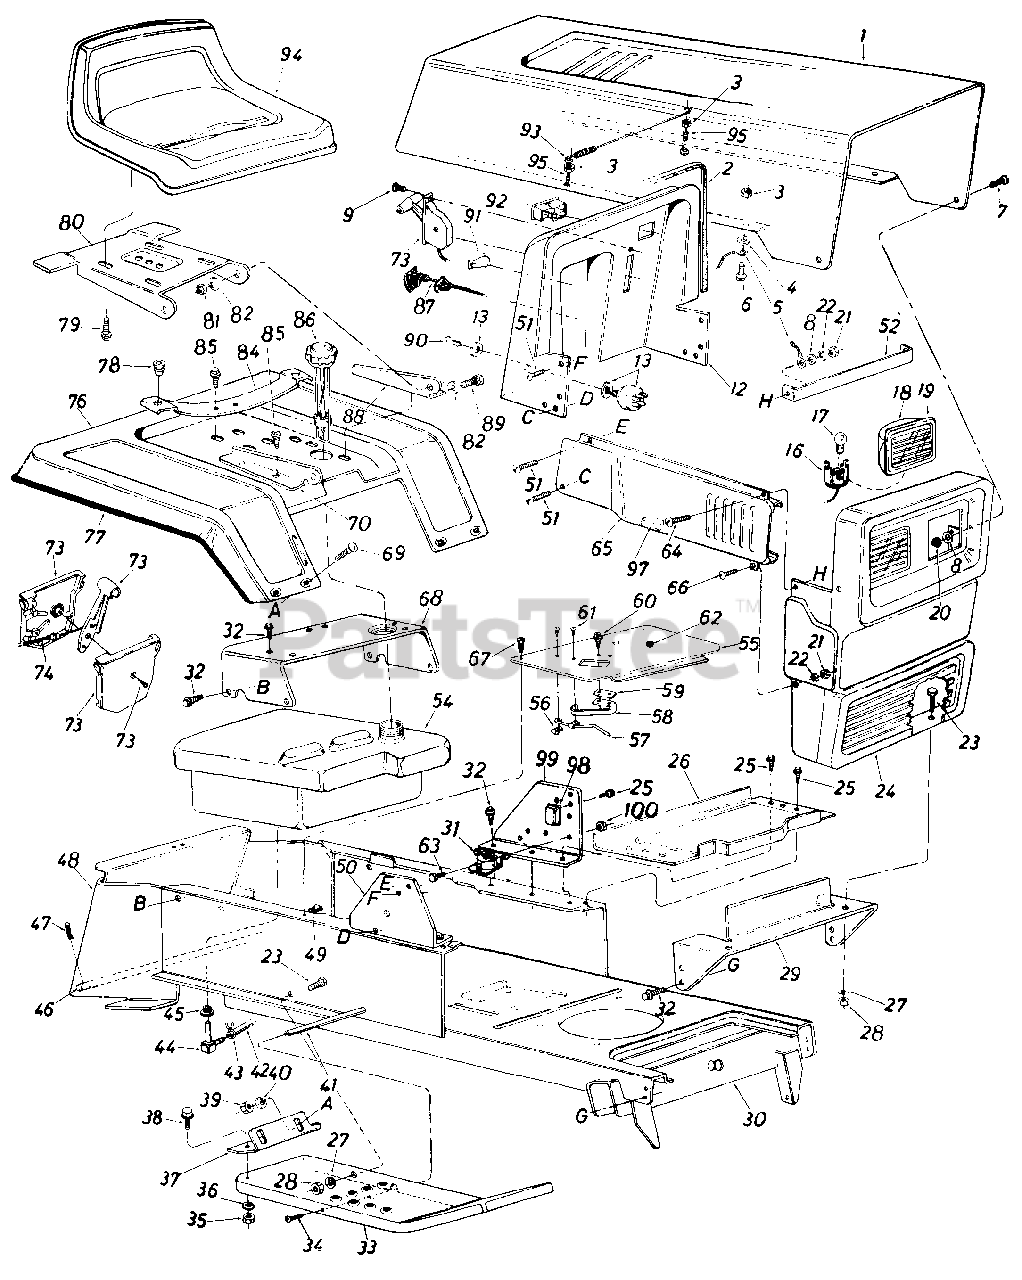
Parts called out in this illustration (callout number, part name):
1	Hood
2	Trim Strip-27" Lg.
3	Hex Sems Nut #10-24 Thd.
4	Fl-Wash. .20" I.D. x .41" O.D.
5	Hood Stop
6	Truss Hd. Mach. Scr. #10-24 x.50" Lg.*
7	Hex Bolt 1/4-20 x .62" Lg.*
8	Fl-Wash. 1/4" I.D.*
9	Truss Mach. AB-Tap Scr. #10 x .50" Lg.
12	Dash Ass'y.
13	Ignition Switch
16	Socket
17	Lamp
18	Headlight Housing
19	Lens
20	Hex L-Nut 1/4-20 Thd.
21	Hex Nut 1/4-20 Thd.*
22	L-Wash. 1/4" I.D.*
23	Hex Bolt 5/16-18 x .75" Lg.*
24	Grille
25	Hex Wash. Hd. Scr. 1/4" x .50" Lg.
26	Battery Plate
27	L-Wash. 5/16" I.D.*
28	Hex Nut 5/16-18 Thd.*
29	Grille Mounting Bracket
30	Lower Frame Ass'y.
31	Solenoid
32	Hex Thd. Rolling Scr. 5/16-24 x .75" Lg.
33	Running Board-R.H.
34	Truss Mach. Scr. 5/16-18 x .75" Lg.*
35	Hex Nut 5/16-18 Thd.*
36	Bell-Wash. .34" I.D. x .87" O.D.
39	Hex Nut 1/4-20 Thd.*
40	L-Wash. 1/4" I.D.*
41	Running Board Rod
42	Fuel Line 40" Lg.
43	Hose Clamp 3/8"
44	90ø Nipple
45	Bushing
46	Hitch Rod
47	Internal Cotterpin
48	Hitch Plate
49	Speed Nut
50	Dash Support Brkt.-R.H.
51	Hex Wash. Hd. Tap Scr. 1/4 x.75" Lg.
52	Tie Strap
54	Fuel Tank
55	Transmission Cover Ass'y.
56	Speed Nut #10-24 U-Type
57	Shift Lever Spring
58	Switch Spring
59	Insulator Plate
60	Hex Wash. Hd. AB-Tap Scr. #18 x .50
61	Truss Mach. Scr. #10 x .50" Lg.
62	Snap Bushing
63	Hex Bolt 1/4-20 x .50" Lg.
64	Truss Hd. Scr. 1/4-20 x .75" Lg.
66	Truss Mach. Scr. 1/4-20 x .50" Lg.
67	Truss Mach. "B" Tap Scr. #10 x .50" Lg.
68	Seat Mounting Channel
69	Carriage Bolt 1/4-20 x .50" Lg.*
70	Seat Bracket-R.H.
73	Throttle Control Box Ass'y.
74	Throttle Control Wire
78	Grommet
79	Hex Wash. Hd. AB-Tap Scr. 318 x .75" Lg.
80	Seat Pivot Bracket
81	Hex Cent. L-Nut 5/16-18 Thd.
82	Belleville Wash. .34" I.D. x .88" O.D.
84	Seat Spring
85	Hex Wash. Hd. Self-Tap Scr. 5/16-18 x .50" Lg.
86	Gas Cap w/Gauge
87	Choke Control Comp.
88	Seat Bracket-L.H.
89	Hex Bolt 5/16-18 x .75" Lg.
90	Ignition Key
91	Light Switch
92	Ammeter
93	Hood Spring
94	Seat Ass'y.
95	Hex Screw #10-24 x 1.0" Lg.
97	Rubber Strip 1/2" Sq. x 2'/2" Lg.
98	Circuit Breaker
99	Dash Support Brkt.-L.H.
100	Hex Sems Nut 1/4-20 Thd.
